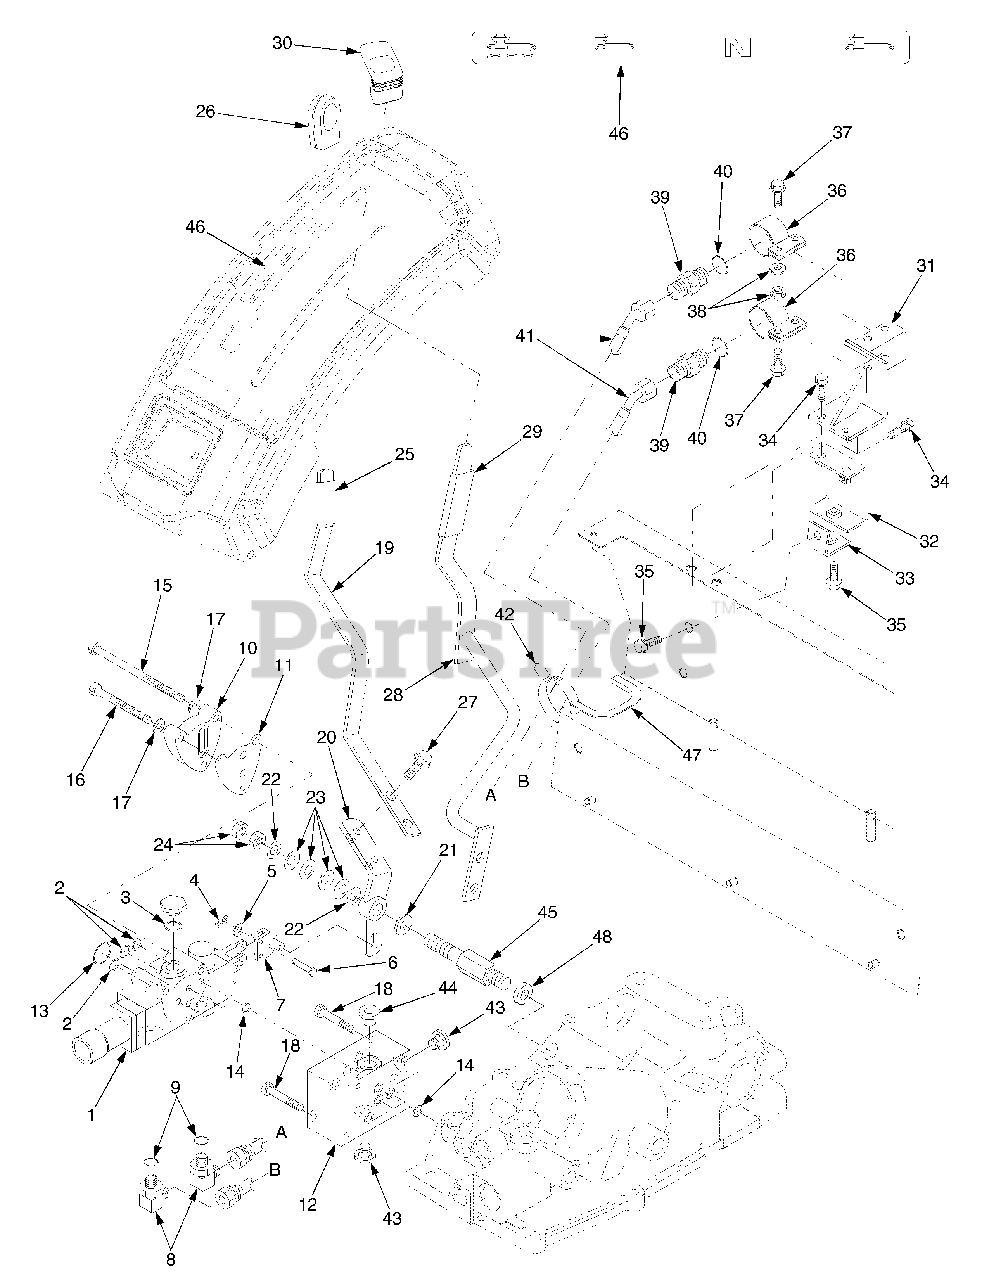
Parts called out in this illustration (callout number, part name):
1	Sub Valve Body Assembly
2	O-Ring
17	Washer, Spring
20	Arm, Aux. Lever
21	Lining, Brake
22	Liner, Thrust
23	Spring Conical
25	Tube, Shift Lever
26	Grip, Range Lever
27	Bolt, w/Washer
28	Lever P/C Position
29	Tube, P/C Lever
31	Bracket, Coupler Clamp
32	Bracket, Support
33	Bracket, Angle
34	Bolt, w/Washer
35	Bolt, w/Washer
36	Clamp, Coupler
37	Bolt, w/Washer
39	Fitting, Adapter
45	Shaft, Aux. Lever
46	Label, Aux. Valve
